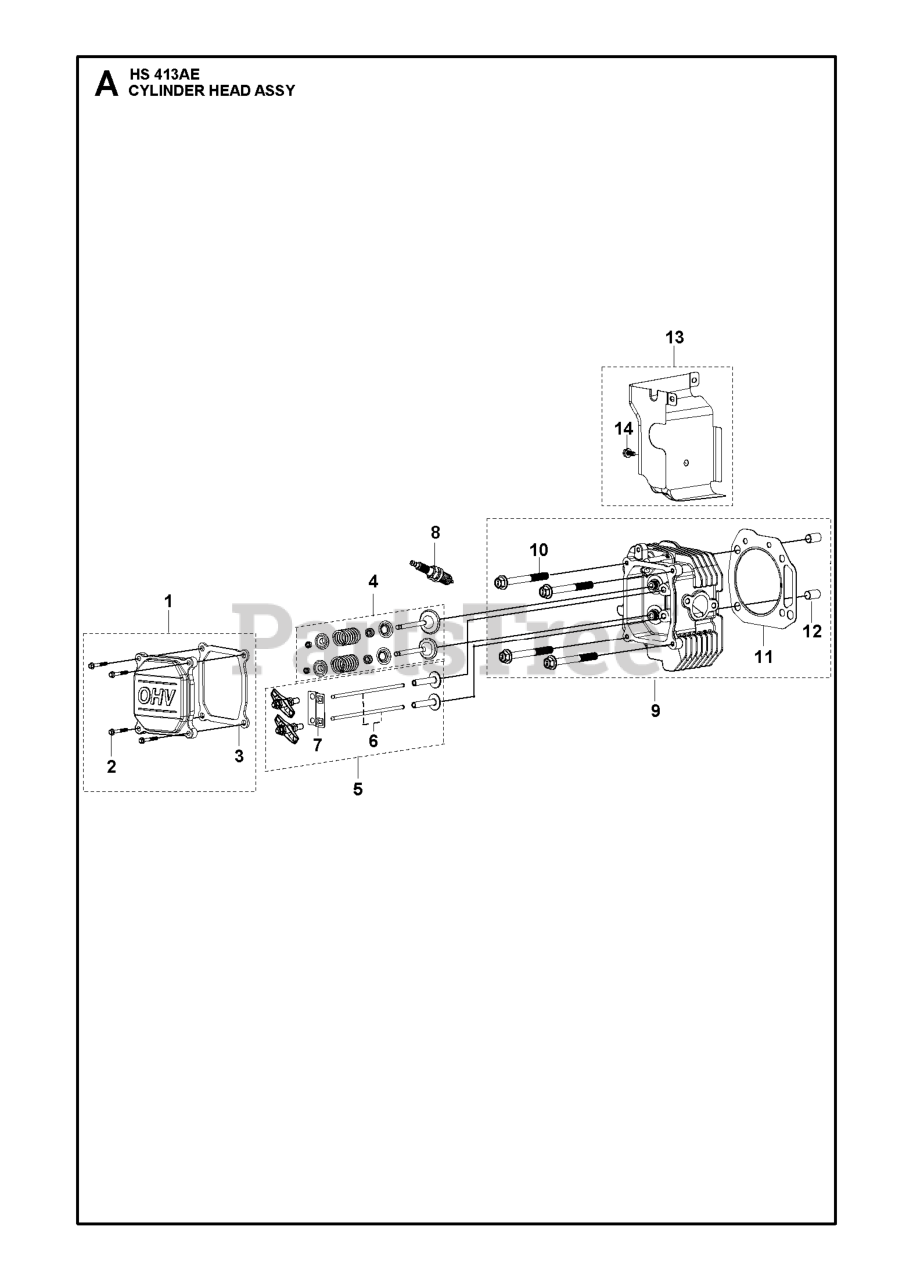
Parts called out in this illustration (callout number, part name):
2	DECAL.HOOD.LOGO.ORANGE.HUSQVAR
3	DECAL.REVERSE.HUSQ
5	DECAL TI (2 2)
6	DECAL.SHIFT.INDICATOR.DRT
7	DECAL.SHIELD.TN.DRT17.HUSQ.008
8	DECAL.FORWARD.HUSQ
9	DECAL.DRT.WARN.ENG/F
